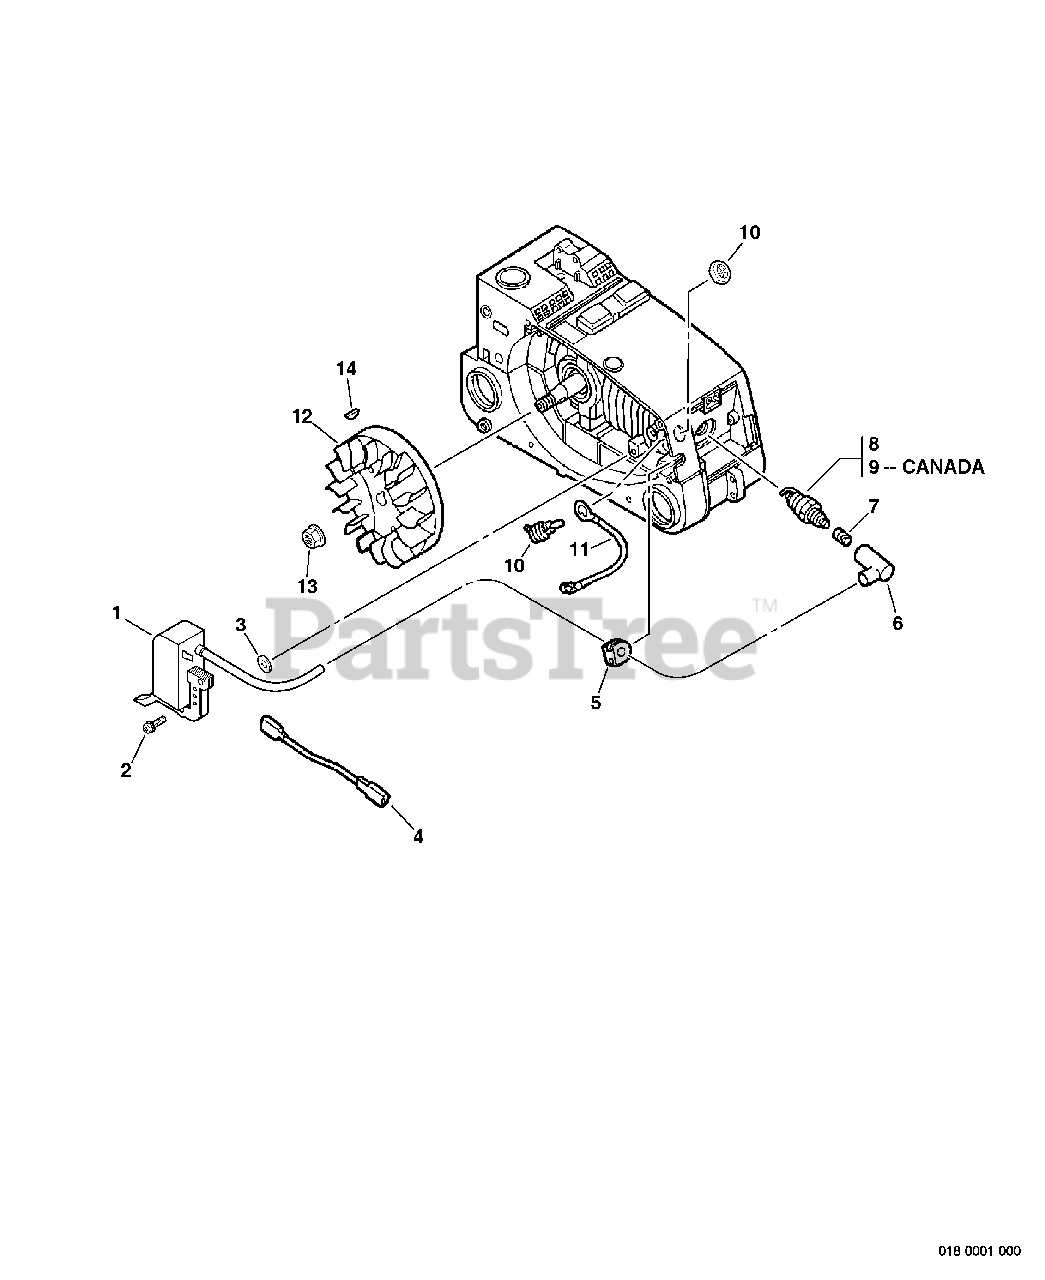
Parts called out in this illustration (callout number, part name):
1	COIL, IGNITION
2	SCREW - 5X22
4	LEAD - IGNITION
6	CAP, SPARK PLUG
7	TERMINAL, SPARK PLUG CAP
8	SPARK PLUG -- BPM-8Y
9	SPARK PLUG -- BPMR-8Y
10	IGNITION SWITCH KIT
11	LEAD - GROUND
12	FLYWHEEL
13	NUT - 8 -- FLANGE
